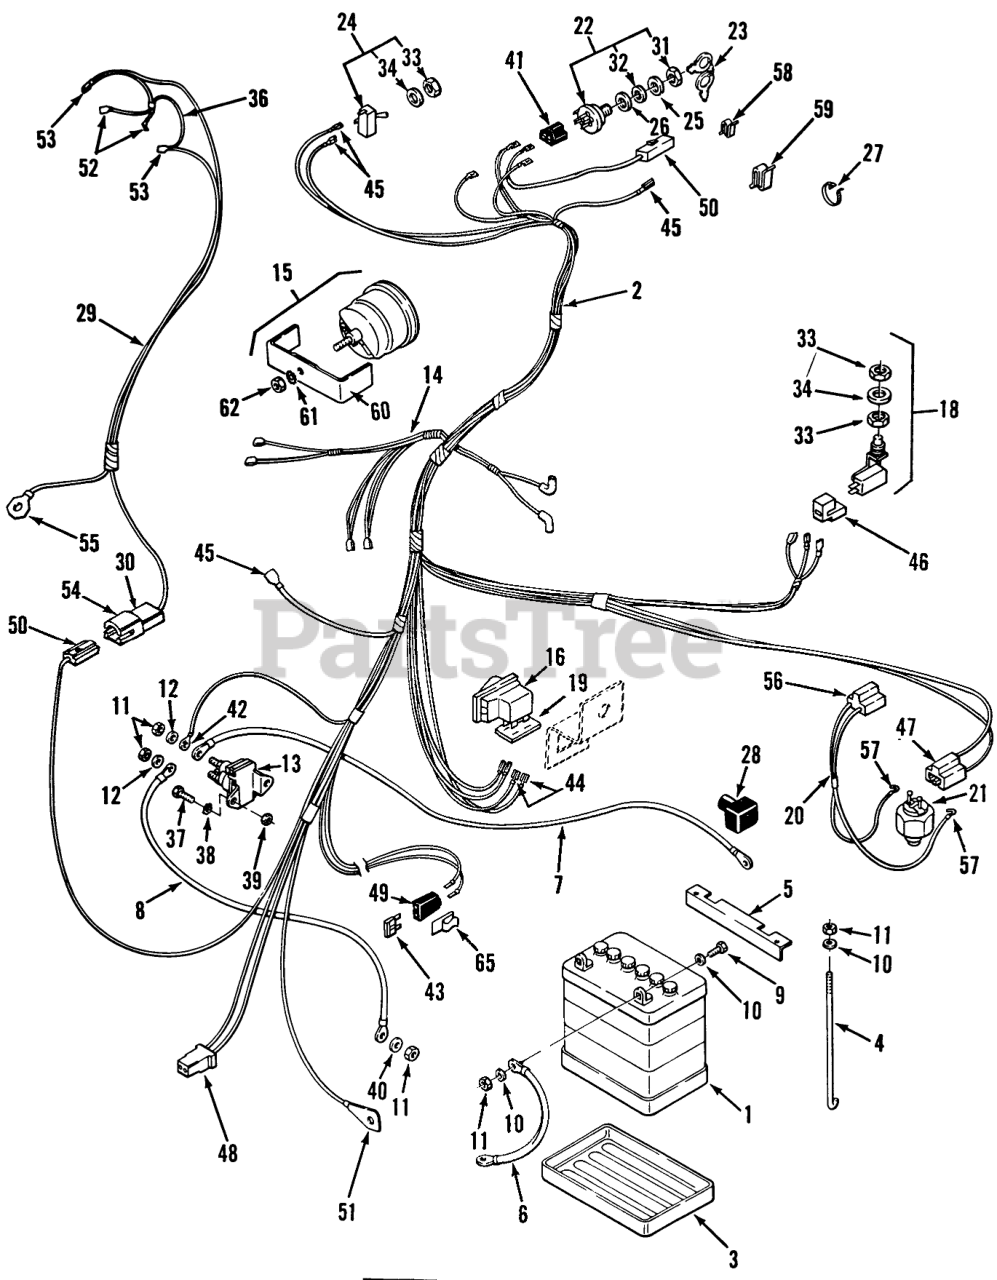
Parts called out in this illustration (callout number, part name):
1	Battery
2	Wiring Harness 211-3
2	Wiring Harness 211-5
3	TRAY BATTERY
5	Battery Angle
6	WIRE -BLACK
7	WIRE - 14" BLACK
8	ASSY WIRE
9	Bolt
11	Nut
12	Washer
13	Solenoid (includes two of item 11)
14	Accessory Wiring Harness 211-5 Only
15	Hourmeter 314, 417
16	PTO Interlock Switch (includes item 19 w/ 109327 PTO Switch)
18	SWITCH-PUSH
19	SHIELD-DIRT (DPDT)
20	ASSY WIRING HARNESS
21	SWITCH (N.C.-TRANS)
22	Ignition Switch (includes items 31 & 32)
23	Ignition Key
24	Light Switch 211-5 Only (includes items 33 & 34).
25	Washer
26	Washer
27	PLASTIC TIE
28	Boot
29	HARNESS
30	Connector (part of item 29)
32	LOCKWASHER
33	NUT-HEX, SPECIAL
34	TAB-WASHER
36	Nut
37	Screw
38	LOCKWASHER
39	Nut
40	Washer
41	5-Terminal Connector (part of item 2)
42	Terminal
43	FUSE-BLADE, 15 AMP
44	Terminal
45	Connector
46	CONNECTOR BODY
47	CONNECTOR BODY
48	Conn Body Part of 7
49	Terminal
50	CONNECTOR BODY ELECT
51	Terminal
52	TERMINAL 10
53	Terminal
54	Connector Part of 5
55	CONNECTOR BODY ELECT
56	CONNECTOR BODY B
57	TERMINAL-TAB RCPT
58	CLIP
59	SPEED CLIP
60	HOUR METER CLAMP
61	Lockwasher
62	Hex Nut
